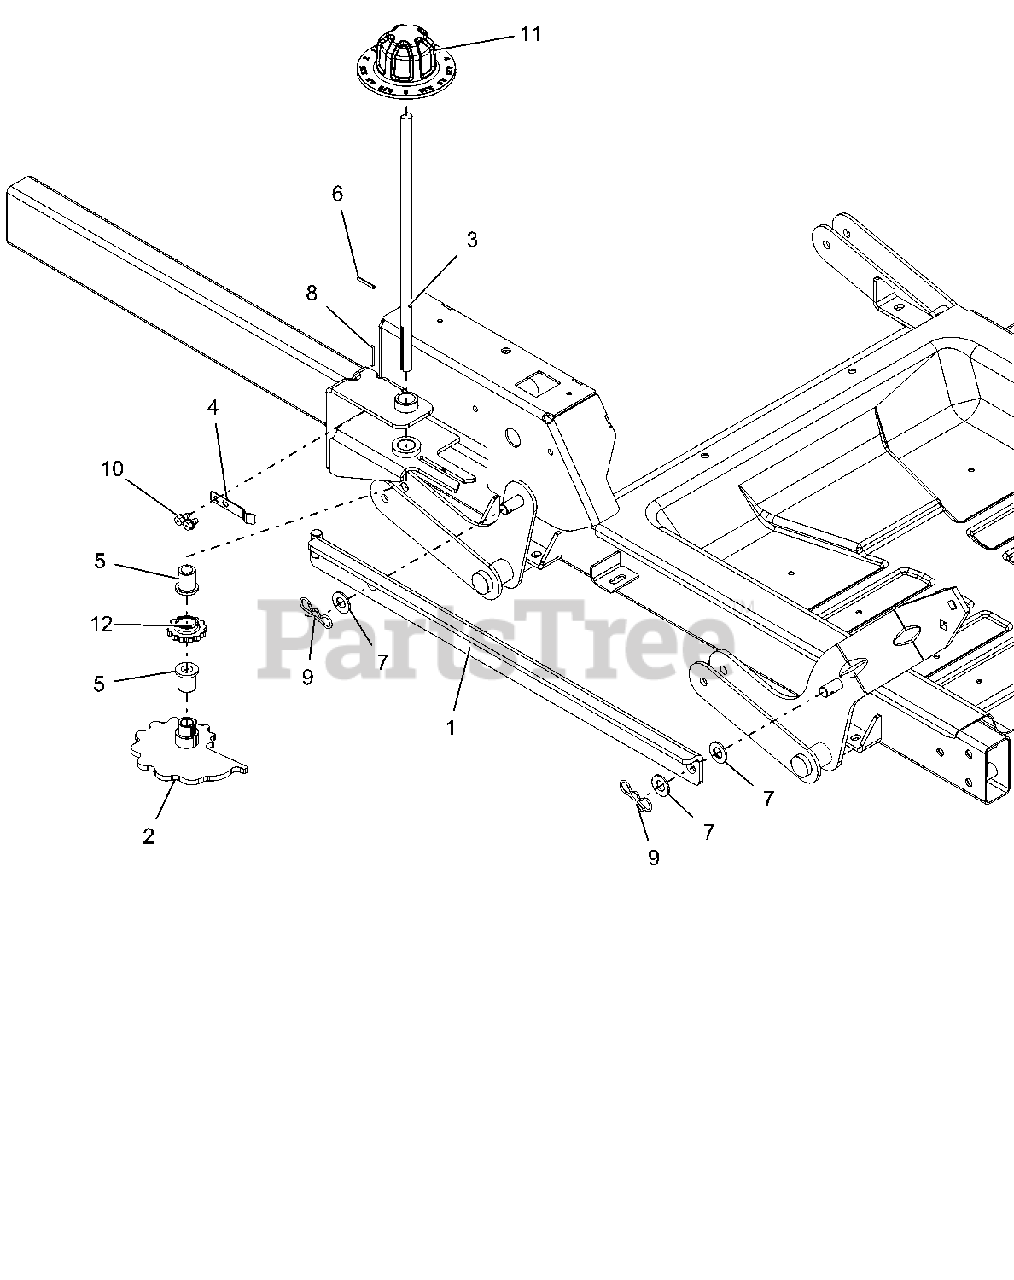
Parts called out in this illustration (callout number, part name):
1	WLDMT, HOC LINK
2	WLDMT, HOC CAM
3	SHAFT, HOC CAM
4	ARM, HOC DETENT
5	BSHG-FLG, .503X.750X.875X1.00
6	PIN-ROLL .125X1.00
7	WSHR-FL-NYL .518X1.000X.080
8	KEY, 1/8 X 1/8 X 1.0
9	PIN,BOW TIE LOCKING .091X1.875
10	@SCR-TAP .25-20X.37 HWH YWZ TR
11	KNOB, HOC
12	GEAR, HOC INDEX
